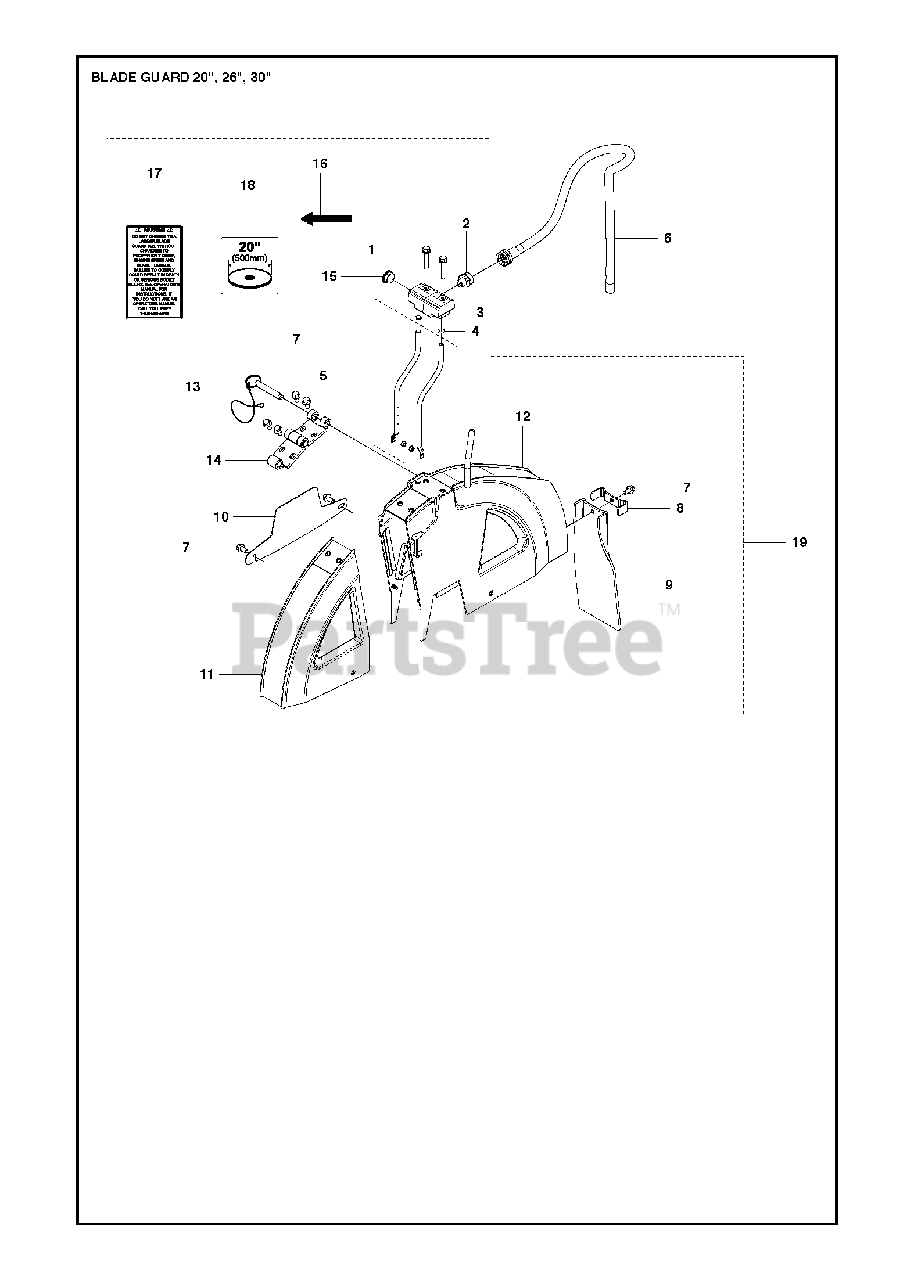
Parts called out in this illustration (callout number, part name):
19	BLADE GUARD500 mm / 20", US
19	BLADE GUARD500 mm / 20", Non US
19	BLADE GUARD650 mm / 26", US
19	BLADE GUARD650 mm / 26", Non US
19	BLADE GUARD750 mm / 30", US
19	BLADE GUARD750mm / 30", Non US
